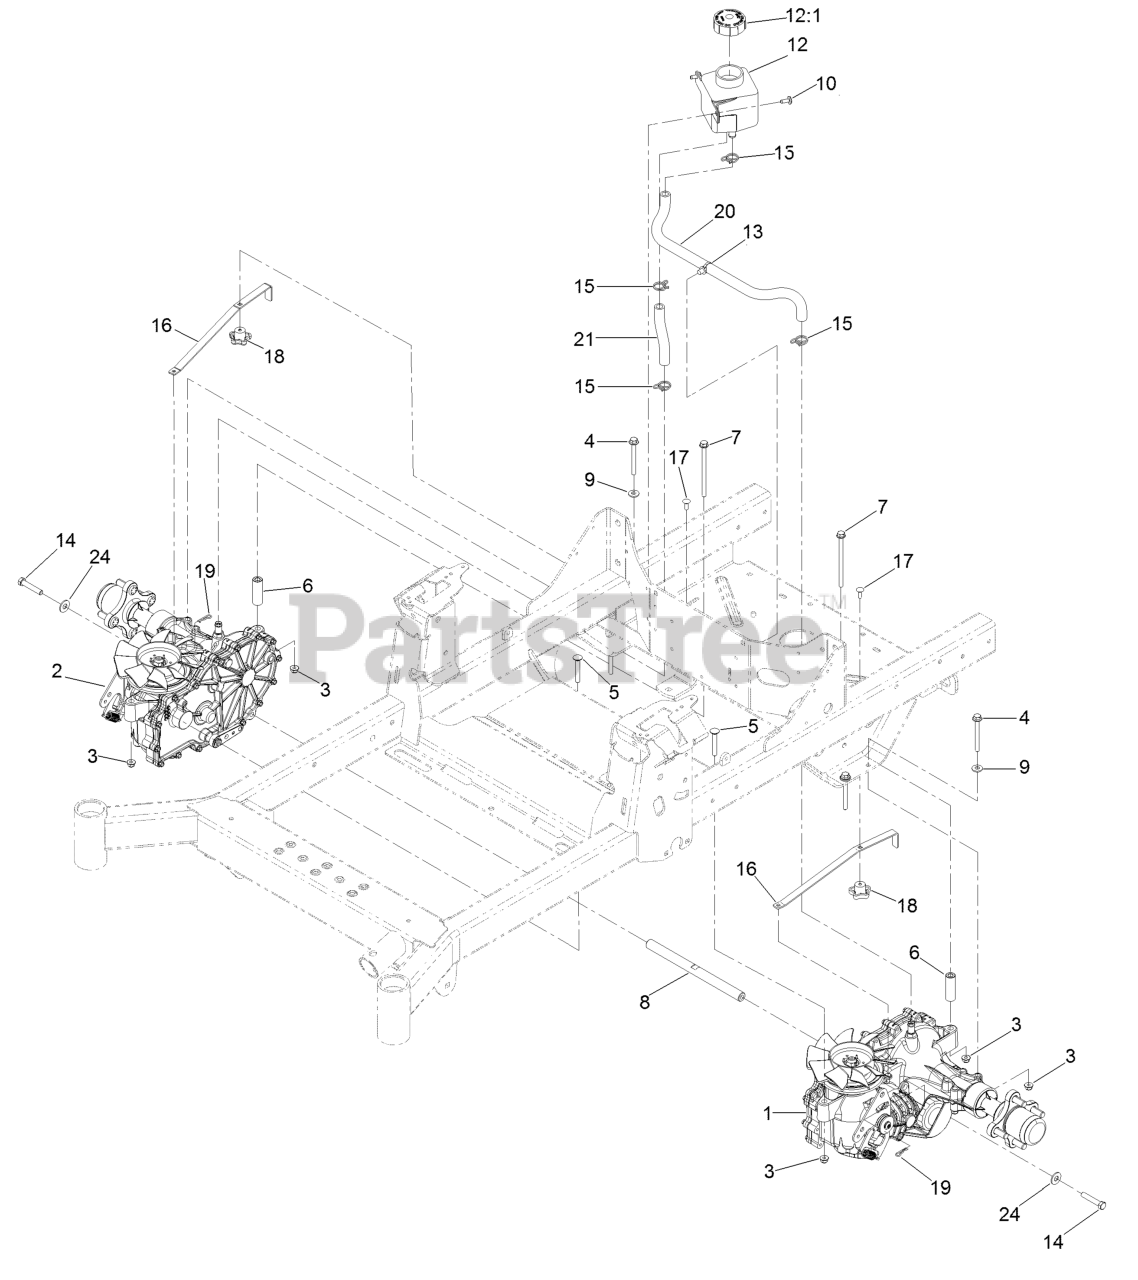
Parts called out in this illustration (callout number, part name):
1	LH TRANSAXLE ASM
2	RH TRANSAXLE ASM
3	NUT-HF, NI
4	SCREW-HHF
5	BOLT-CARR
6	SPACER-HYDRO
7	SCREW HHF
8	SHAFT-SPACER
9	WASHER-SPRING
10	SCREW-TORX
12	TANK-HYD
12:1	CAP-RESERVOIR, HYD
13	CLIP-TIE
14	SCREW-HH W/LOCTITE
15	CLAMP-HOSE
16	ARM-BYPASS, HYDRO
17	BOLT-CARR
18	KNOB-HANDLE
19	PIN-COTTER
20	HOSE-HYDRAULIC
21	HOSE-HYDRAULIC
24	WASHER-FLAT
